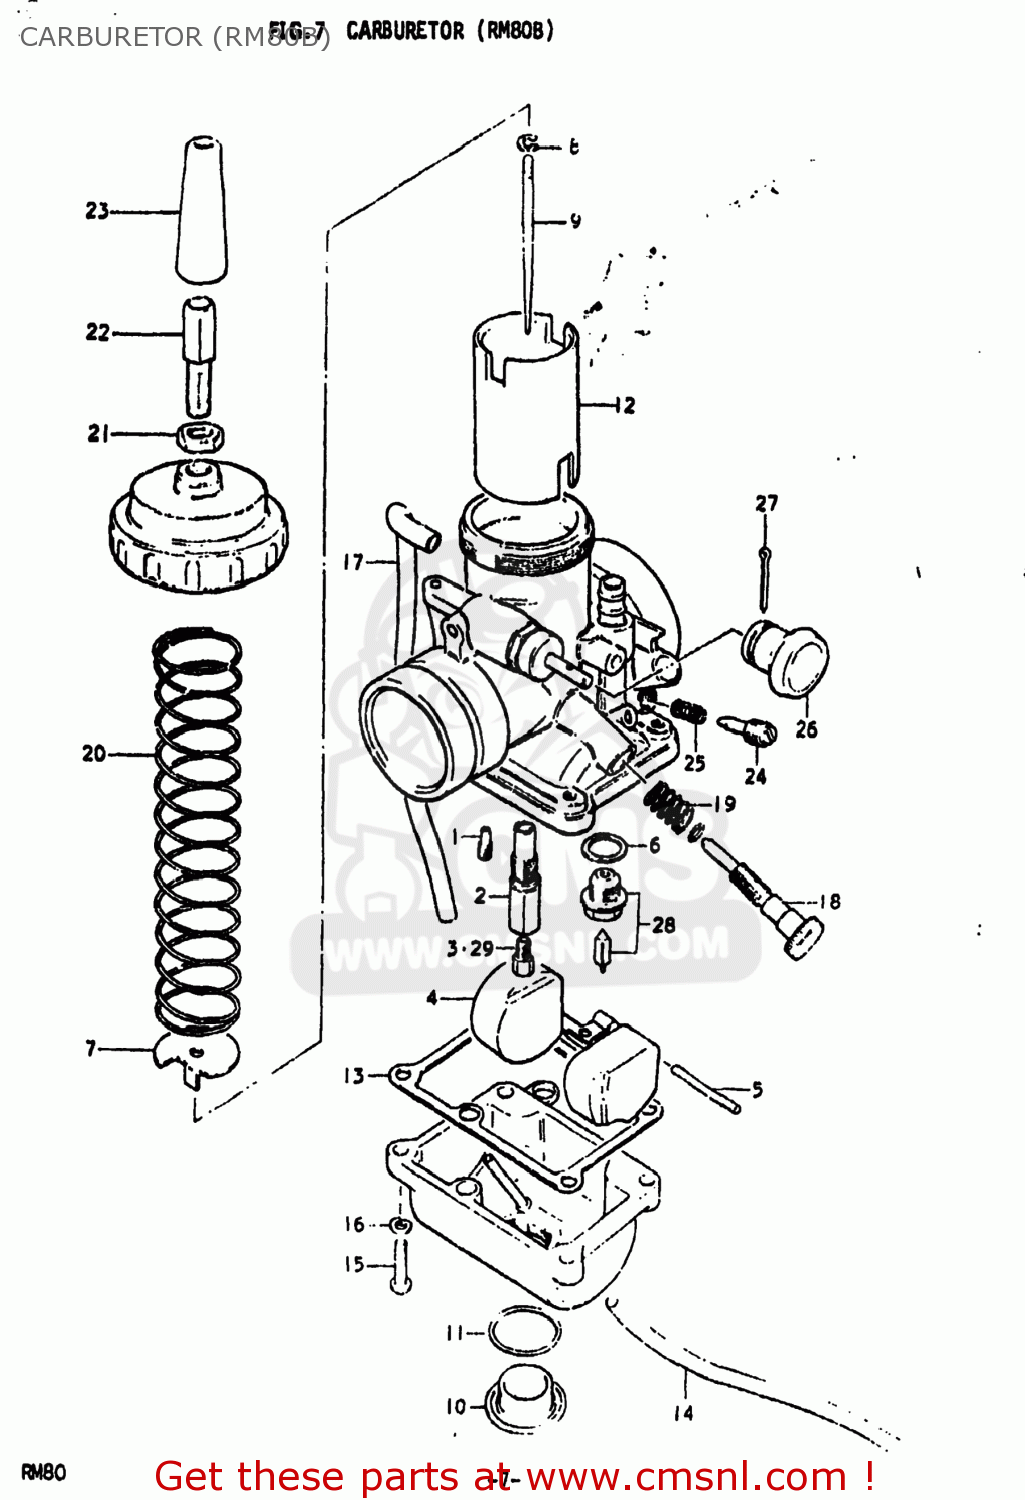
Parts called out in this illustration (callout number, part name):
1	JET
2	JET,NEEDLE
3	JET, MAIN
4	FLOAT
5	PIN,FLOAT
6	GASKET (NAS)
7	SEAT,THROTTLE VALVE SPRING
8	CLIP
9	NEEDLE,JET
10	SCREW,GUIDE
11	O-RING
12	VALVE,THROTTLE
13	GASKET,FLOAT CHAMBER (NAS)
14	HOSE
15	SCREW
16	LOCK WASHER
17	HOSE
18	ADJUSTER
19	SPRING
20	SPRING, THROTTLE VALVE
21	NUT
22	ADJUSTER,CABLE
23	CAP,CABLE ADJUSTER
24	SCREW,PILOT AIR
25	SPRING
26	LEVER
27	COTTER PIN
28	VALVE ASSY,NEEDLE
29	JET
